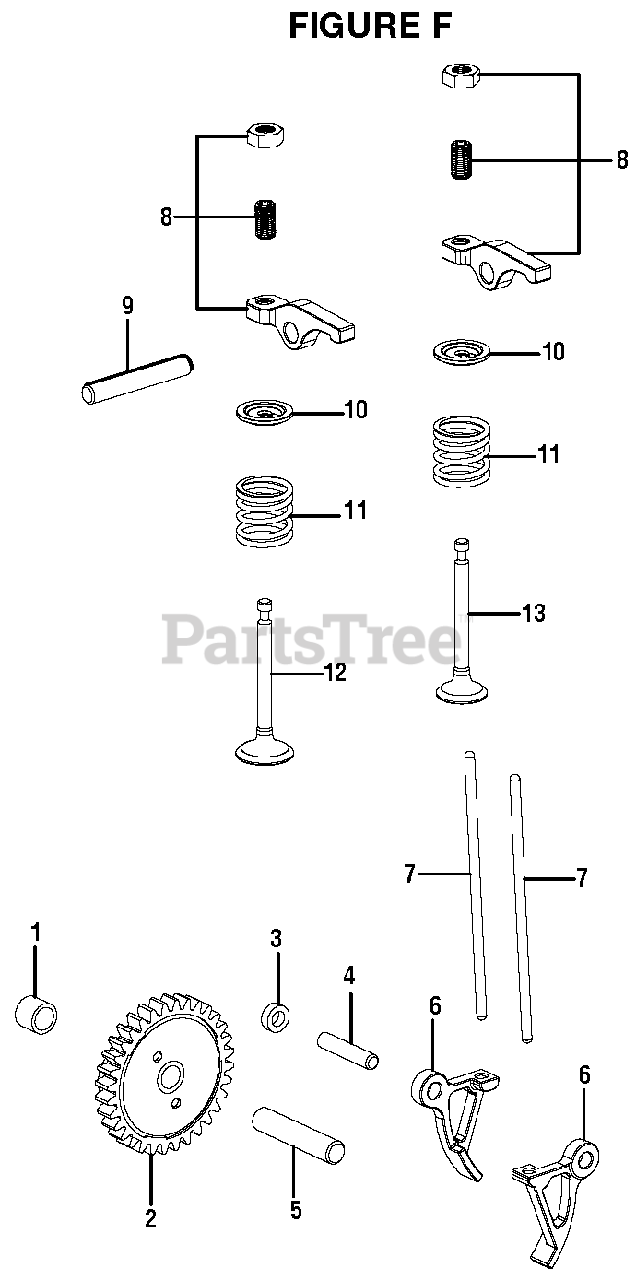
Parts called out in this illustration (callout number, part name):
3	Rocker Gasket
4	Pin (G4 x 20 mm)
5	Pin (G6 x 30 mm)
8	Upper Rocker Assembly
9	Pin (G6 x 32 mm)
10	Valve Spring Seat
13	Exhaust Valve
